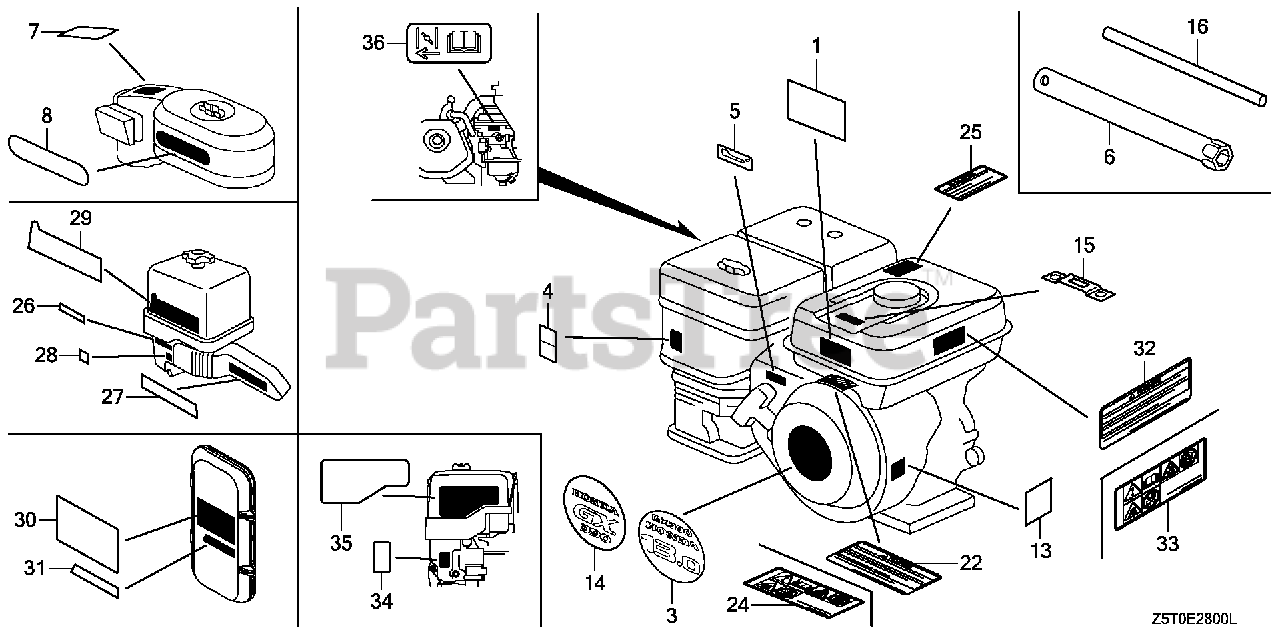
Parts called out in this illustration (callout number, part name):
1	MARK, OPERATOR CAUTION (PICTOGRAPH)(MADE IN JAPAN)
1	MARK, OPERATOR CAUTION (Honda Code 8018954). (ENGLISH)(MADE IN THAILAND)
1	MARK, OPERATOR CAUTION (ENGLISH)(MADE IN THAI)
1	MARK, OPERATOR CAUTION (Honda Code 8018970). (PICTOGRAPH)(MADE IN THAILAND) (NOT AVAILABLE)
4	MARK, CHOKE
5	MARK, THROTTLE INDICATION
6	WRENCH, SPARK PLUG
14	EMBLEM (GX390) (HONDA)
25	MARK, EX. CAUTION (ENGLISH)
